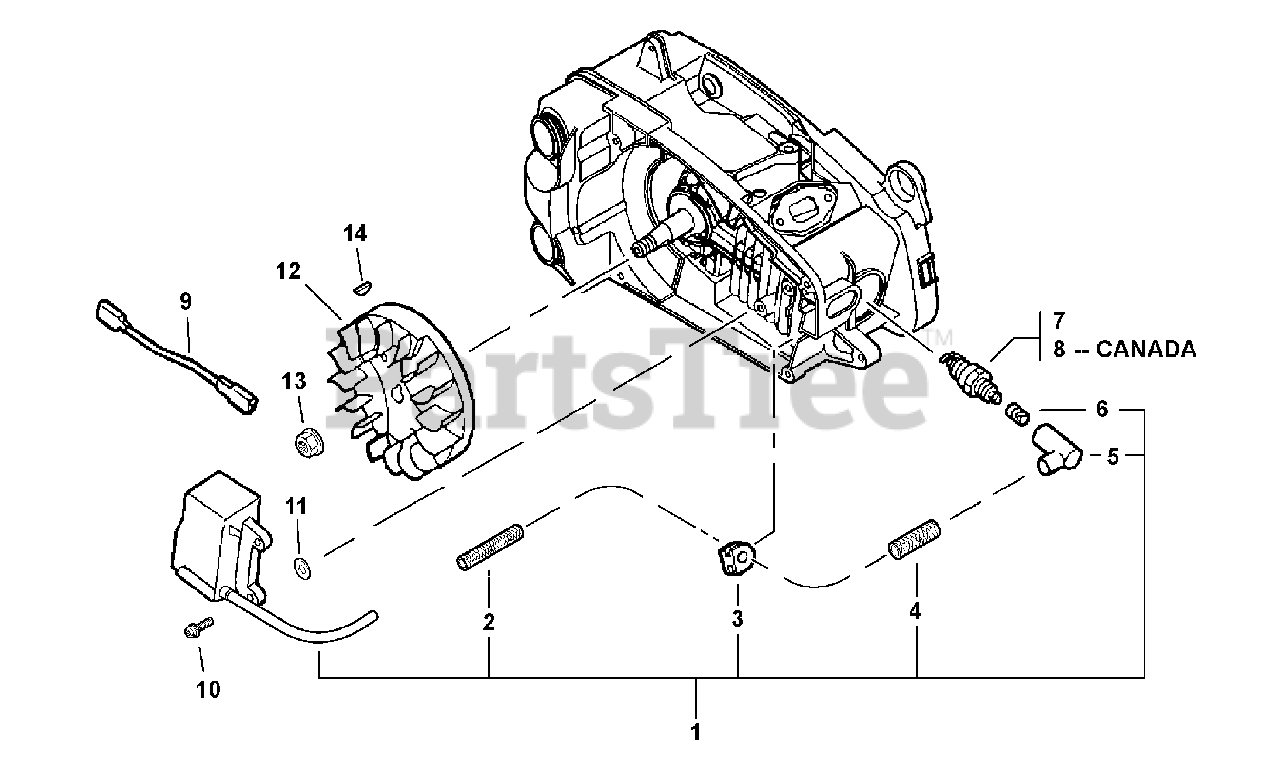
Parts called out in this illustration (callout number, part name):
1	COIL, IGNITION
2	TUBE, INSULATOR
4	TUBE, INSULATOR
5	CAP, SPARK PLUG
6	TERMINAL, SPARK PLUG CAP
7	SPARK PLUG -- BPM-8Y
8	SPARK PLUG -- BPMR-8Y
9	LEAD - IGNITION
10	SCREW - 5X22
12	FLYWHEEL
13	NUT - 8 -- FLANGE
